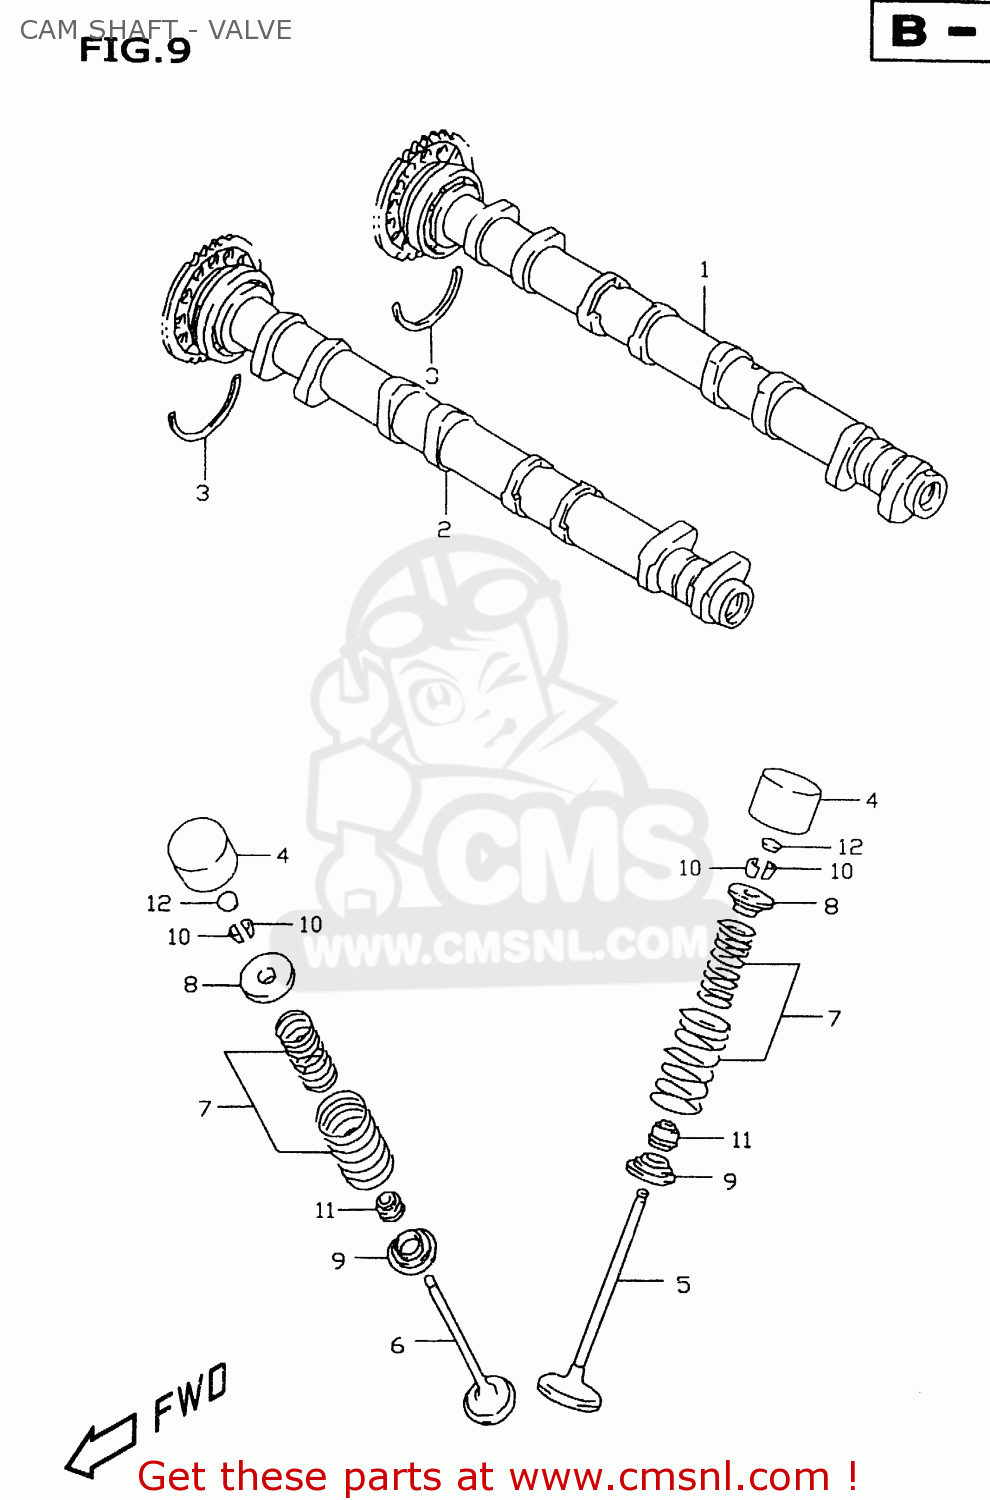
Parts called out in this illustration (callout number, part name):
1	CAMSHAFT,INTAKE
2	CAMSHAFT,EXHAUST
3	C RING
4	TAPPET
5	VALVE,INTAKE
6	VALVE,EXHAUST
7	SPRING SET,VALVE
8	RETAINER,VALVE SPRING
9	SEAT,VALVE SPRING
10	COTTER VALVE
11	SEAL,OIL(4.5X10X8)
12	SHIM,TAPPET
